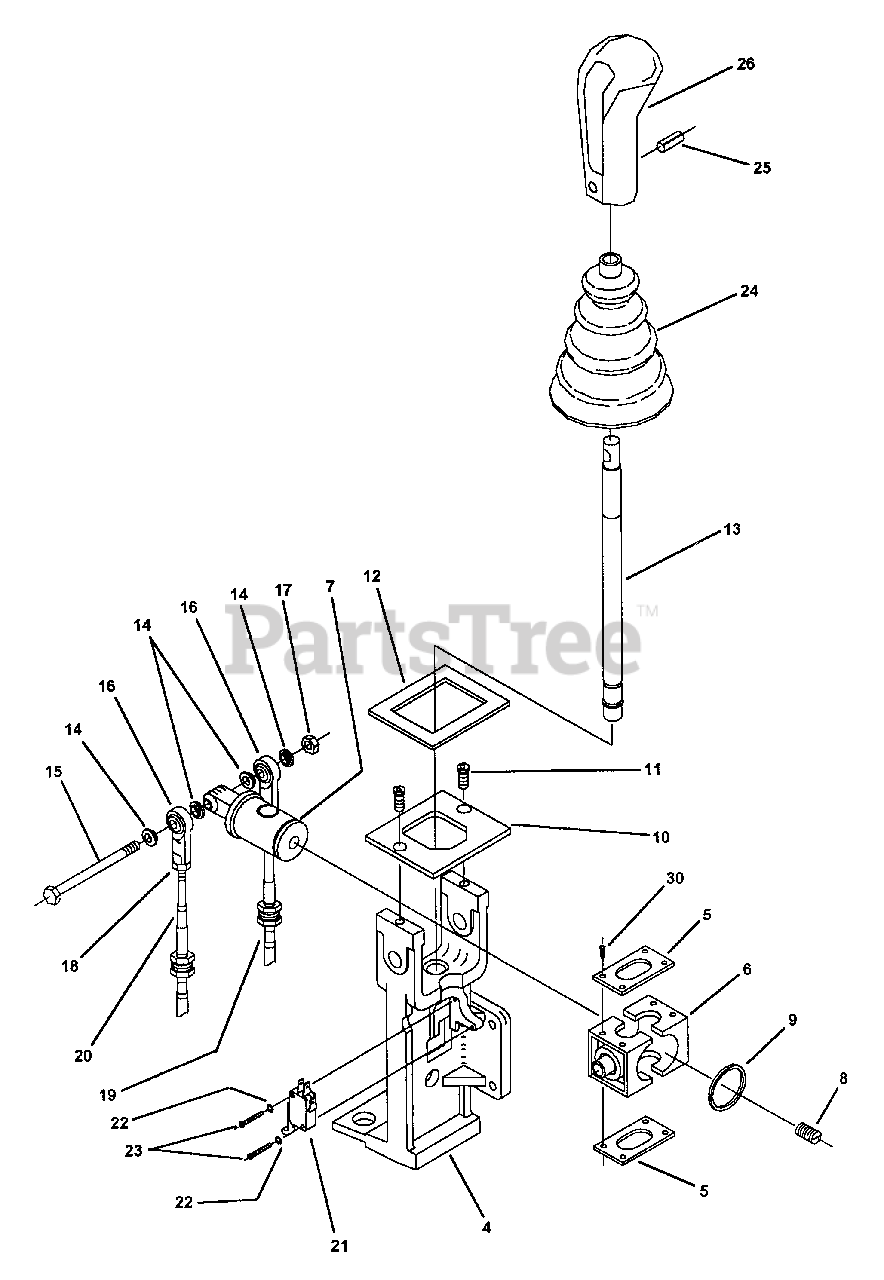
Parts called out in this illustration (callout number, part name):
4	JOYSTICK YOKE
5	PIVOT BLOCK PLATE, JOYSTICK
6	PIVOT BLOCK, Delrin Plastic
7	PIVOT SHAFT, Delrin Plastic
8	BALL PLUNGER, 3/8-16 X 5/8"
9	SNAP RING, SPIRLOCK
10	TOP PLATE, JOYSTICK
11	SCREW, 1/4-20 X 1/2", FLATHEAD
12	GASKET, FOAM
13	JOYSTICK SHAFT ASSEMBLY
14	BUSHING, BALL JOINT
15	CAP SCREW, 1/4-20 X 3", HEX HEAD
16	BALL JOINT, 1/4-28, FEMALE
17	NUT, 1/4-20, NYLOCK
18	NUT, 1/4-28, (comes with 26 & 27)
19	PUSH-PULL CABLE, 58"
20	PUSH-PULL CABLE, 42"
21	SWITCH, SPDT, MINIATURE
22	LOCK WASHER, & STAR
23	SCREW, #4-40 X 3/4"
24	BELLOWS BOOT
25	ROLL PIN, 3/16 X 1"
26	HANDLE GRIP
30	SCREW, #6-32 X 3/8", TYPE B POINT, SLOTTED HD.
